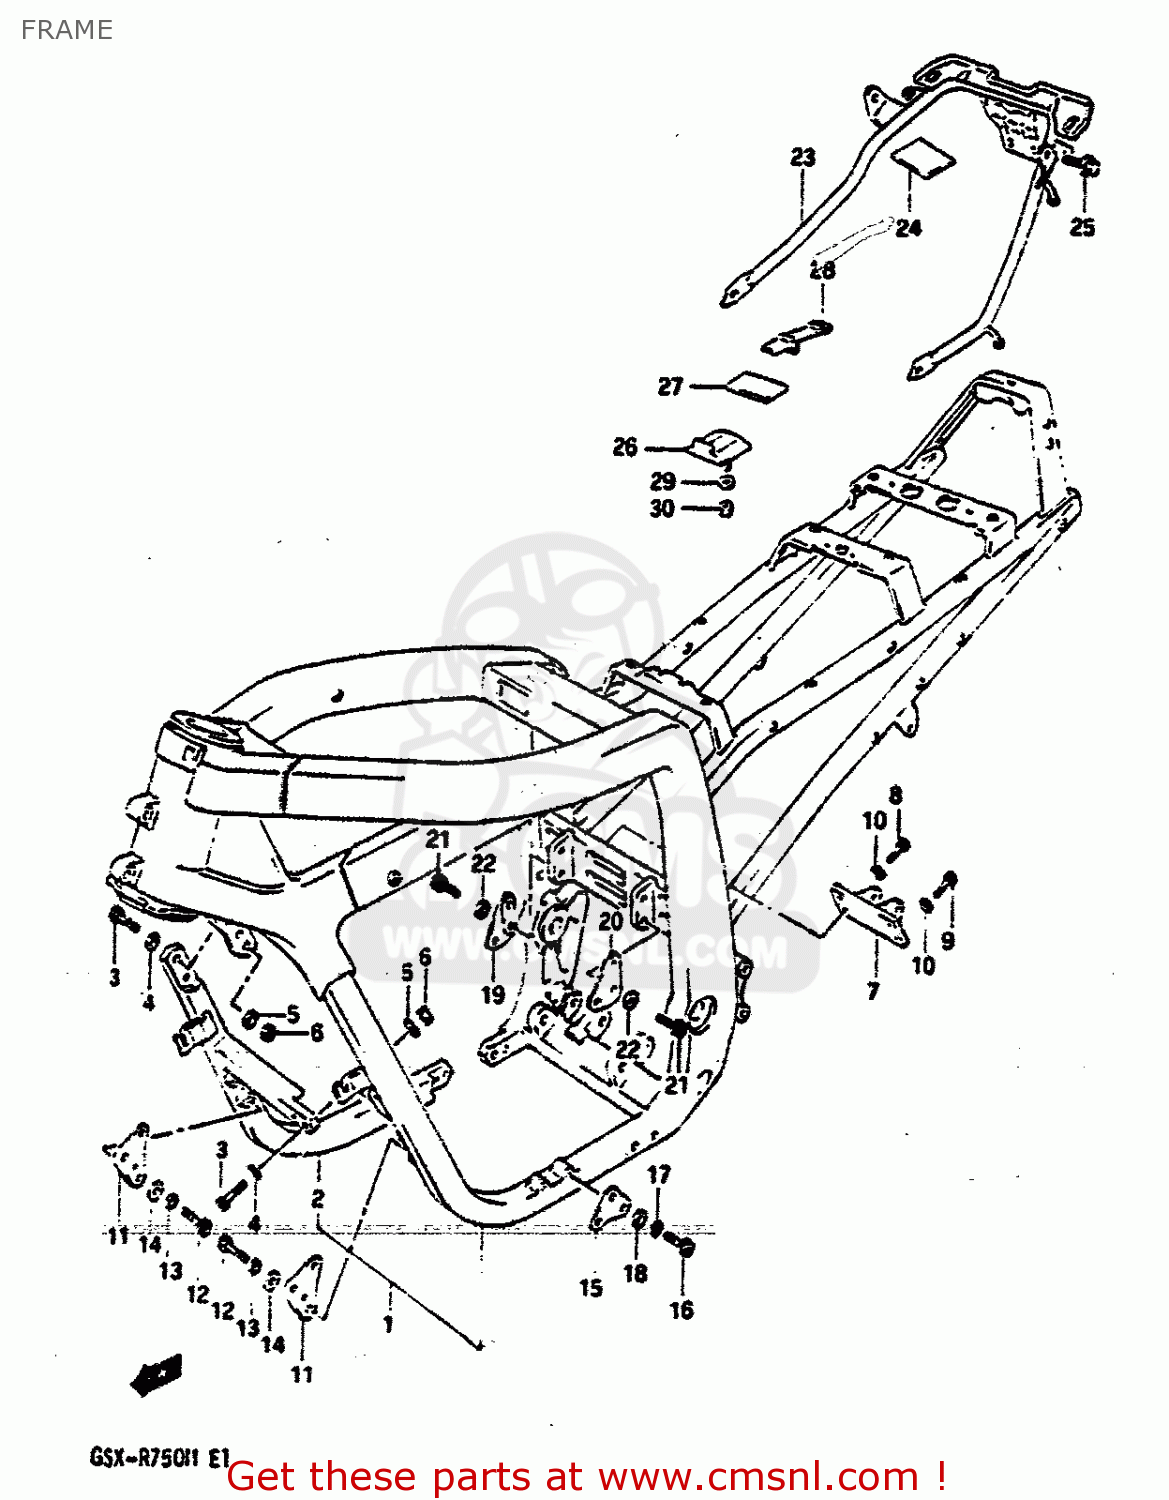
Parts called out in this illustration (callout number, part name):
1	2
2	TUBE,FRAME
3	BOLT, LH
4	WASHER (10.1X21X2.3)
5	WASHER
6	NUT
7	BRACKET,RCU
8	BOLT 10X27
9	BOLT, LH
10	WASHER
11	PLATE,ENGINE MOUNTING
12	BOLT, FRONT LH
13	WASHER,LOCK
14	WASHER (8.2X20X1.6)
15	PLATE,ENGINE MOUNT NO.2
16	BOLT, FRONT LH
17	WASHER,LOCK
18	WASHER (8.2X20X1.6)
19	PLATE,ENGINE MOUNT NO.3,R
20	PLATE,ENGINE MOUNTING NO
21	BOLT(8X22)
22	WASHER (8.2X20X1.6)
23	GRIP,RR
24	TAPE,FRAME PROTECTOR
25	BOLT
26	HOLDER,TOOL
27	CUSHION
28	BAND
29	WASHER
30	NUT 6MM
